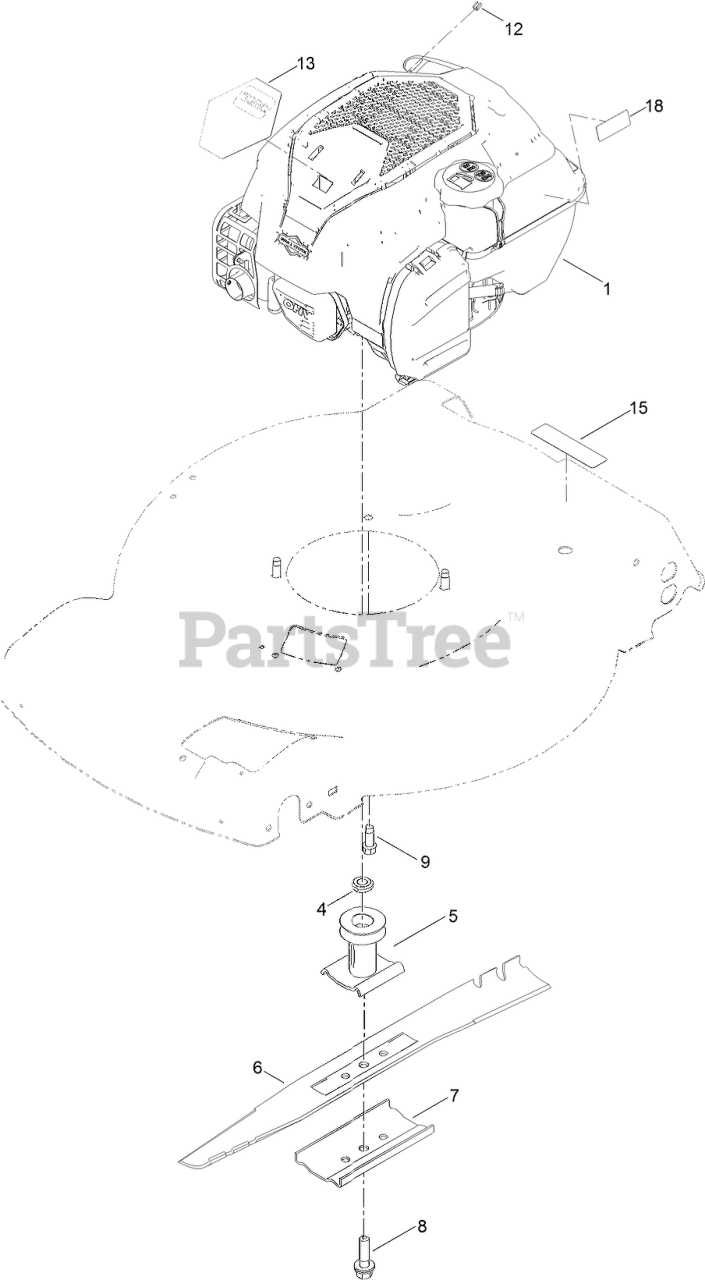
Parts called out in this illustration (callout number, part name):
4	SPACER-DRIVER
5	DRIVER-BLADE
6	BLADE-22 INCH
7	SUPPORT-BLADE
8	BOLT-BLADE
9	SCREW-TAPTITE
12	STOP-ROPE
13	DECAL-SHROUD
15	DECAL-ARRESTOR, SPARK
18	DECAL-LEVEL, FUEL
